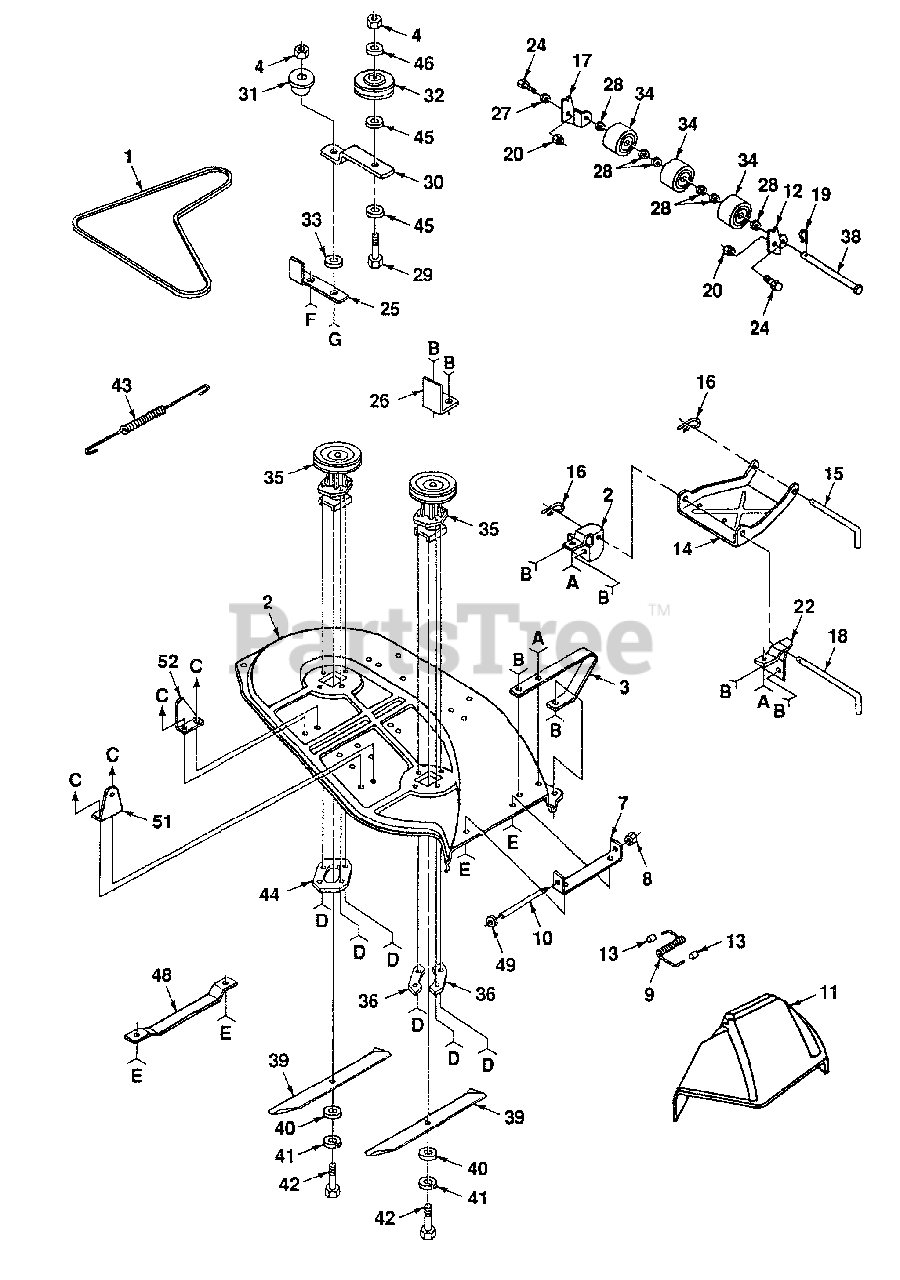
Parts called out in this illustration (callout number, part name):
2	Housing Assembly
3	Runner, R.H.
4	Nut, Crownlock 3/8 - 16
7	Bracket, Deflector
9	Spring, Deflector
10	Rod, Hinge
11	Deflector, Shield
12	Bracket, Nose Roller, R.H.
13	Cap, Sleeve
14	Link, Parallel
15	Pin, Hinge, Front
16	Spring, Retainer
17	Bracket, Nose Roller, L.H.
18	Pin, Hinge, Rear
19	Pin, Cotter 1/8 x 3/4
20	Nut, Crownlock 5/16 - 18
22	Bracket, Lift, L.H.
24	Bolt, Hex 5/16 - 18 x 1/4
25	Support, Arm
26	Stop, Deck, Front
27	Washer 1/2 x 1 x 16 Gauge
28	Washer 15/32 x 1 x 10 Gauge
29	Bolt 3/8 - 16 x 2
30	Arm, Idler
32	Pulley, Idler
33	Washer, Wear 1/16"
34	Roller, Nose
35	Mandrel Assembly
36	Plate, Support, Mandrel
38	Pin, Pivot
39	Blade, Mower, Hi-Lift
40	Washer 13/32 x 1-1/4 x 12 Gauge
41	Washer, Lock 3/8
42	Bolt, Hex 3/8 - 24 x 1-1/2 Grade 5
43	Spring, Extension
44	Plate, Support, Mandrel
45	Washer 13/32 x 3/4 x 10 Gauge
46	Washer 13/32 x 13/16 x 16 Gauge
48	Runner, L.H.
49	Washer 11/32 x 5/8 x 16 Gauge
51	Bracket, Suspension, Rear, R.H.
52	Bracket, Suspension, Rear, L.H.
